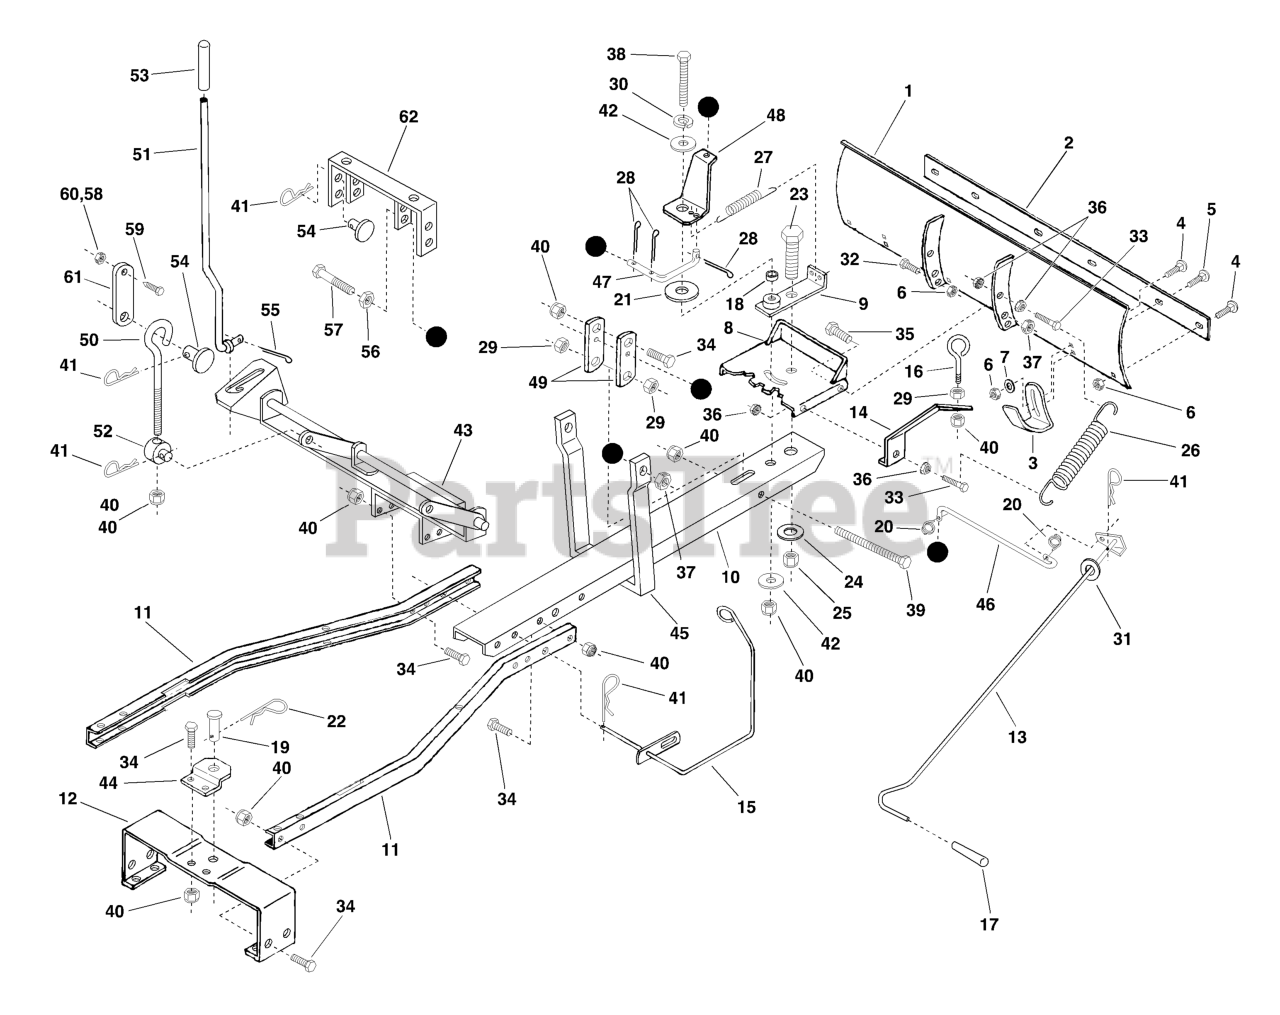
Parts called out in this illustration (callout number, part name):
1	46" Blade
2	Plate, Wear Strip 46"
3	Skid, Shoe
4	Bolt, Carriage 5/16-18 x 3/4"
5	Bolt, Carriage 5/16-18 x 1"
6	Nut, Hex Lock 5/16-18
7	Washer, Flat 5/16"
8	Plate, Pivot
9	Bracket, Pivot Reinforcement
10	Channel, Thrust
11	Channel, Rear Support
12	Bracket, Rear Mounting
13	Handle, Pivot Control
14	Bracket, Blade Pivot
15	Pivot Handle Support Assembly
16	Bolt, Eye 3/8-16 x 2" (5/8" I.D.)
17	Grip, 3/8" I.D. x 3" LG.
18	Spacer, 3/8" I.D. x 1/2" O.D.
19	Pin, Clevis 5/8" x 1-3/4"
20	Clip, Spring
21	Washer, Flat .53" x 2" x 0.88"
22	Pin, Hair Cotter 5/32" Dia.
23	Bolt, Hex 5/8-11 x 1-3/4"
24	Washer, Flat 21/32" x 1-5/16"
25	Nut, Hex 5/8-11 (Nylock)
26	Spring, Blade Return
27	Spring, Idler
28	Pin, Cotter 3/32" x 3/4"
29	Nut, Hex 3/8-16
30	Lockwasher, 3/8"
31	Washer, Flat 3/8"
32	Bolt, Hex 5/16-18 x 5/8"
33	Bolt, Hex 5/16-18 x 1-1/4"
34	Bolt, Hex 3/8-16 x 1"
35	Bolt, Hex 1/2-13 x 1"
36	Nut, Hex 5/16-18 (SIMS)
37	Nut, Hex Lock 1/2-13
38	Bolt, Hex 3/8-16 x 2-1/2"
39	Bolt, Hex 3/8-16 x 4-1/2"
40	Nut, Hex 3/8-16 (NYLOCK)
41	Pin, Hair Cotter 3/32" Dia.
42	Washer, Flat .406" x 1-1/2"
43	Lift Bracket Assembly
44	Bracket, Rear Locating
45	Stabilizer, Front
46	Rod, Pivot Release (RH)
47	Rod, Pivot Control (RH)
48	Bracket, Pivot Release (RH)
50	Bolt, Eye 3/8-16 x 7" LG.
51	Lift Handle Assembly
52	Trunnion
53	Grip, 1/2" I.D. x 3" LG.
54	Pin, Clevis 1/2" x 1"
55	Pin, Cotter 1/8" x 1-1/4"
56	Nut, Jam 1/2-13
57	Bolt, Hex 1/2-13 x 1-3/4"
58	Nut, Hex 5/16-18 Serrated Flanged
59	Screw, 1/4-20 Thread Forming
60	Nut, Hex Lock 1/4-20
61	Strap, Lift Anchor
62	Bracket, Stabilizer
